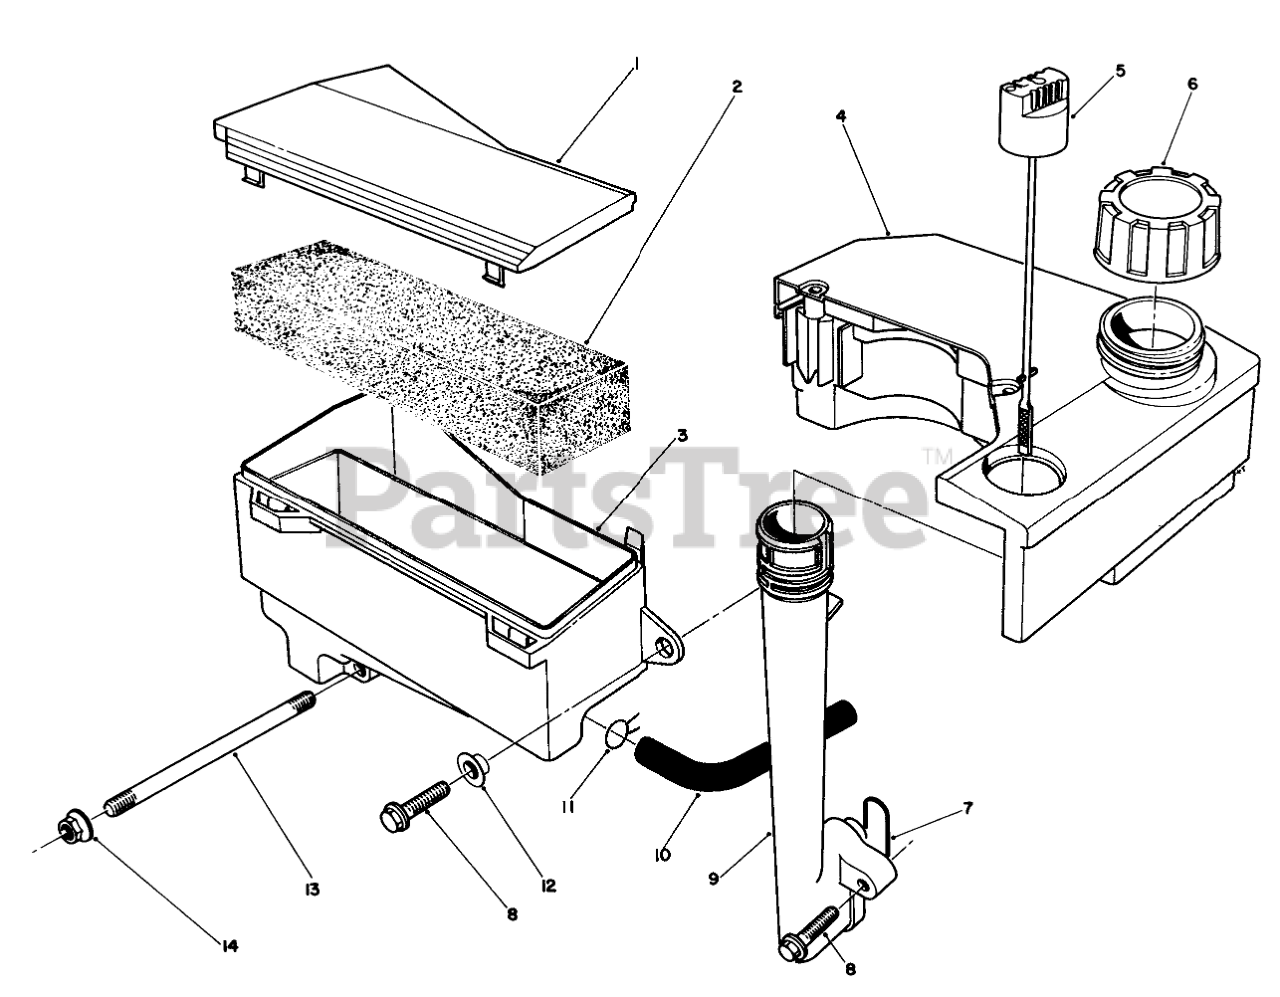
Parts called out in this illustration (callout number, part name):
1	AIR CLEANER CAP
3	Air Cleaner Assembly (Incl. Ref. #1)
4	TANK ASM
5	Dipstick
6	GAS CAP ASM
7	O-RING
11	CLAMP F/W ENGINE
12	SPACER
13	Stud-Carburetor
